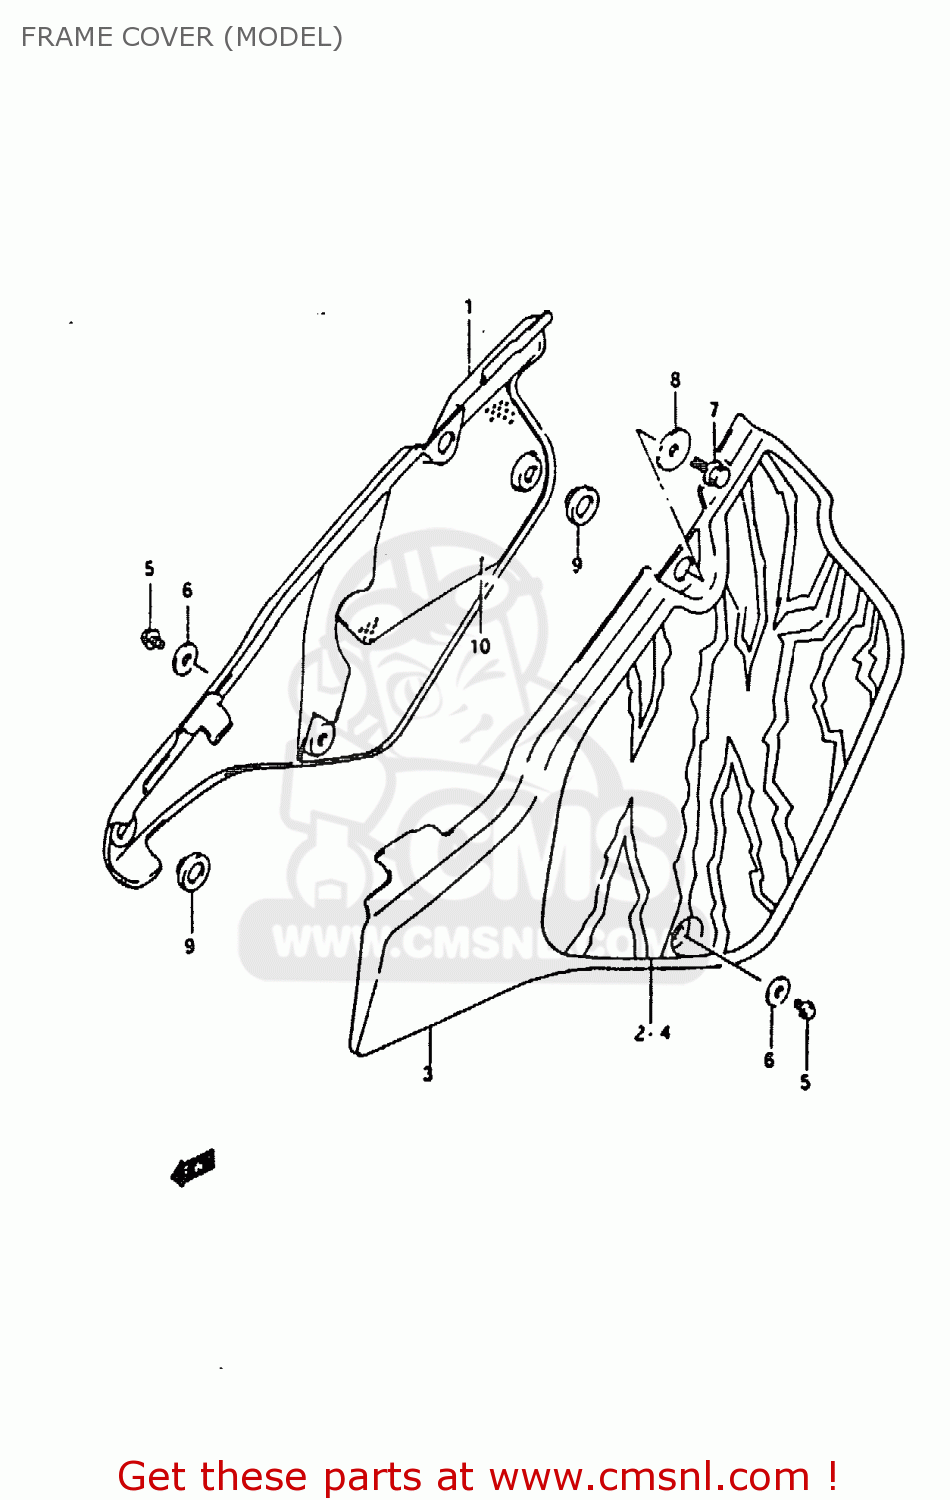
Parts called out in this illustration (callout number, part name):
1	COVER,FRAME,R(WHITE)
2	TAPE,FRAME COVER,RIGHT
3	COVER,FRAME,L(WHITE)
4	TAPE,FRAME COVER,LEFT
5	BOLT
6	GASKET(6.5X20X1.5) (NAS)
7	BOLT
8	WASHER
9	CUSHION
10	HEATSHIELD,FRAME COVER,R
13	HEATSHIELD,FRAME COVER,R
